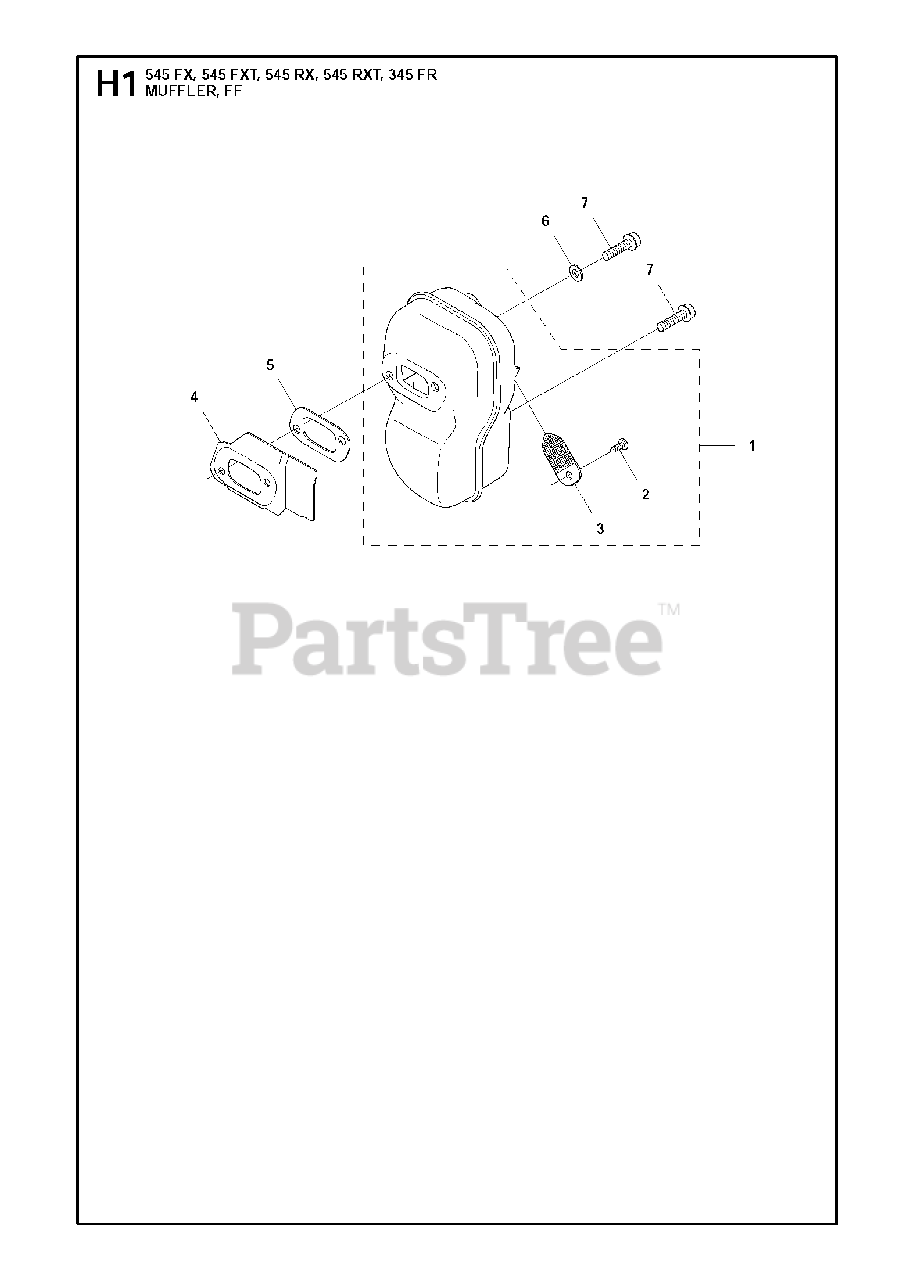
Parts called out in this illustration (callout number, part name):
1	MUFFLER KIT EXHAUST DUCT
2	SCREW
3	SPARK ARRESTOR SCREEN
4	HEAT DEFLECTOR
6	DOUBLE WASHER
